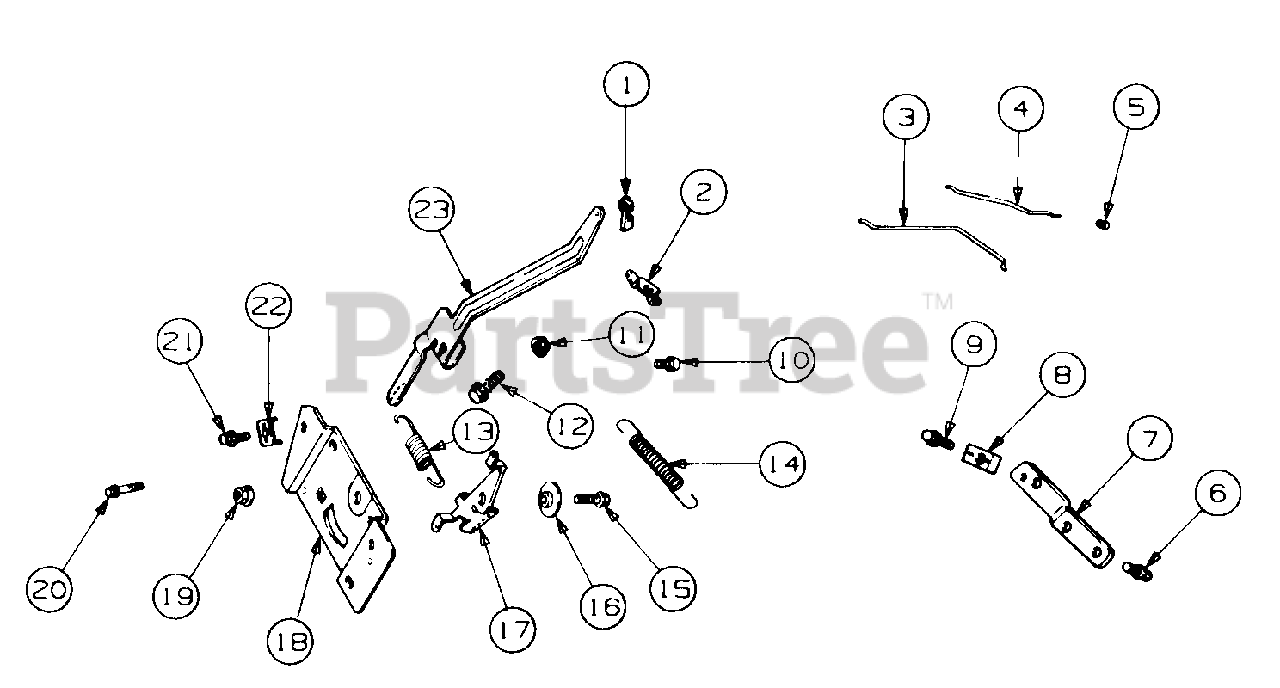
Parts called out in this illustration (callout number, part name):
1	Bushing, Throttle
2	Lever, Choke, Upper
3	Linkage, Choke, Upper
4	Linkage, Throttle
5	Bushing, Linkage
6	Screw, Bracket, M5 x 0.8 x 10
7	Bracket, Choke Mount
8	Clamp, Cable
9	Screw, Clamp, M5 x 0.8 x 16
10	Screw, M5 x 0.8 x 10
11	Nut, M6 x 1.0
12	Screw, Gov Arm, M6 x 1.0 x 25
13	Spring, Governor
14	Spring, Linkage
15	Screw, Throttle Control M5 x 0.8 x 16
16	Spacer, Throttle Control
17	Lever, Throttle Control
18	Plate, Control
19	Nut, Hex, M5 x 0.8
20	Screw, Control Plate, M6 x 1.0 x 16
21	Screw, Cable Clamp, M5 x 0.8 x 16
22	Clamp, Cable
23	Lever, Governor
